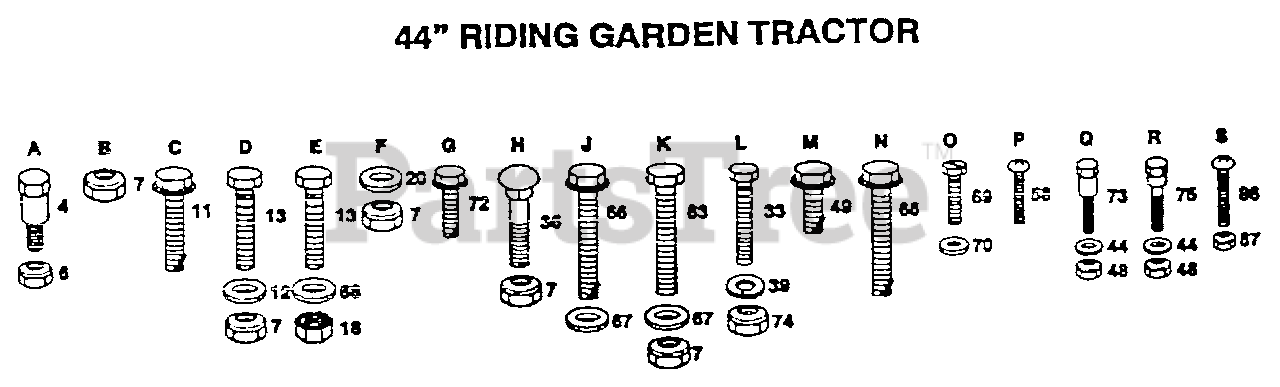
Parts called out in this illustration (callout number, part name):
11	SCREW
12	WASHER
18	NUT
20	WASHER
33	BOLT LT
36	BOLT
39	LOCKWASHER
49	SCREW LT
63	BOLT
66	SCREW GTV
67	WASHER HYT
68	WASHER
69	SCREW
73	BOLT T
75	"BOLT,SHOULDER"
87	"NUT,KEPS"
